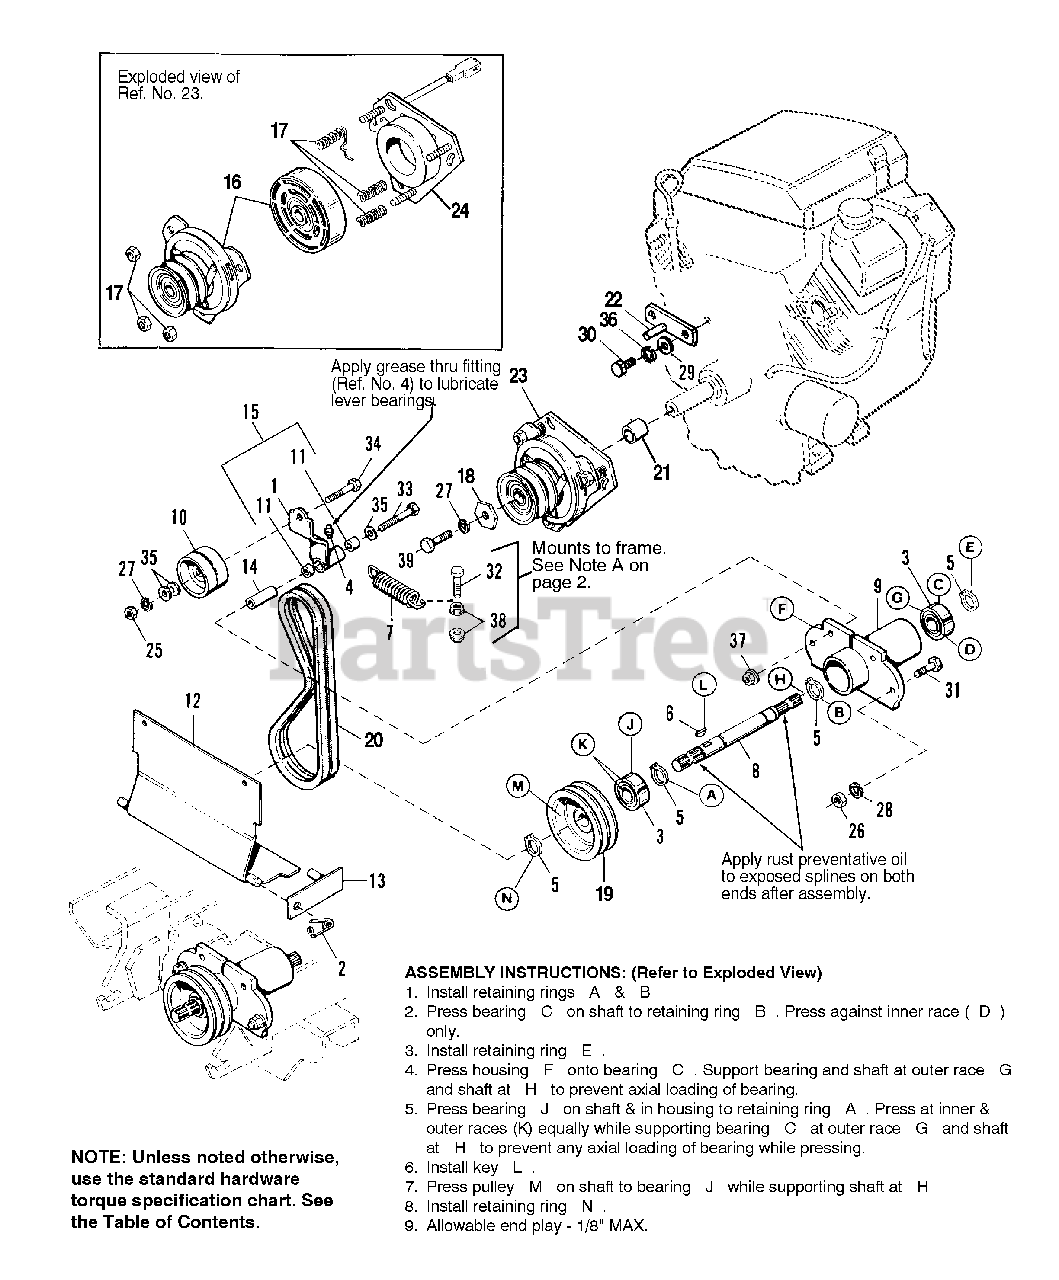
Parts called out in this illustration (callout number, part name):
2	CLIP, Pin, Safety
3	BEARING, Ball, 1-3/16 x 2-7/16 x 5/8
4	FITTING, Grease
5	RING
6	KEY, HI PRO, 1/4 x 3/4
7	SPRING, Tension
8	SHAFT, Spline, PTO
9	HOUSING & PLATE ASSY.
10	PULLEY, Idler, 3-1/4 Dia.
11	BUSHING, Idler Arm
12	GUARD ASSY.
13	LINK & PIN ASSY., Guard
14	SPACER, 3/8 x 5/8 x 1-3/4
15	IDLER ARM ASSY.
16	ROTOR ASSY. & ARMATURE ASSY. KIT
17	ACCESSORY KIT
18	WASHER, Hex
19	PULLEY, PTO Drive
20	BELT SET, PTO Drive (Matched Set of 2)
22	PLATE ASSY.
23	ELECTRIC CLUTCH (PTO)
24	FIELD ASSY.
25	NUT, Hex, 3/8-16
26	NUT, Hex, 1/2-13
27	LOCKWASHER, 3/8
28	LOCKWASHER, 1/2
29	LOCKWASHER, 15/32
30	CAPSCREW, 7/16-14 x 1
31	CAPSCREW, Hex Hd., 1/2-13 x 1-1/4, Gr. 5
32	CAPSCREW, Hex Hd., 3/8-16 x 1-3/4
33	SCREW, Hex Hd., 3/8-16 x 2-1/2, Gr. 5
34	SCREW, Hex Hd., 3/8-16 x 2
35	WASHER, 13/32
36	WASHER, 15/32 I.D. x 15/16 O.D. x 7/64 Thk.
37	NUT, Hex, Flange, 3/8-16
38	NUT, Hex, Flange Whizlock, 3/8-16
39	SCREW, Hex Hd., 3/8-24 x 2, Gr. 5
